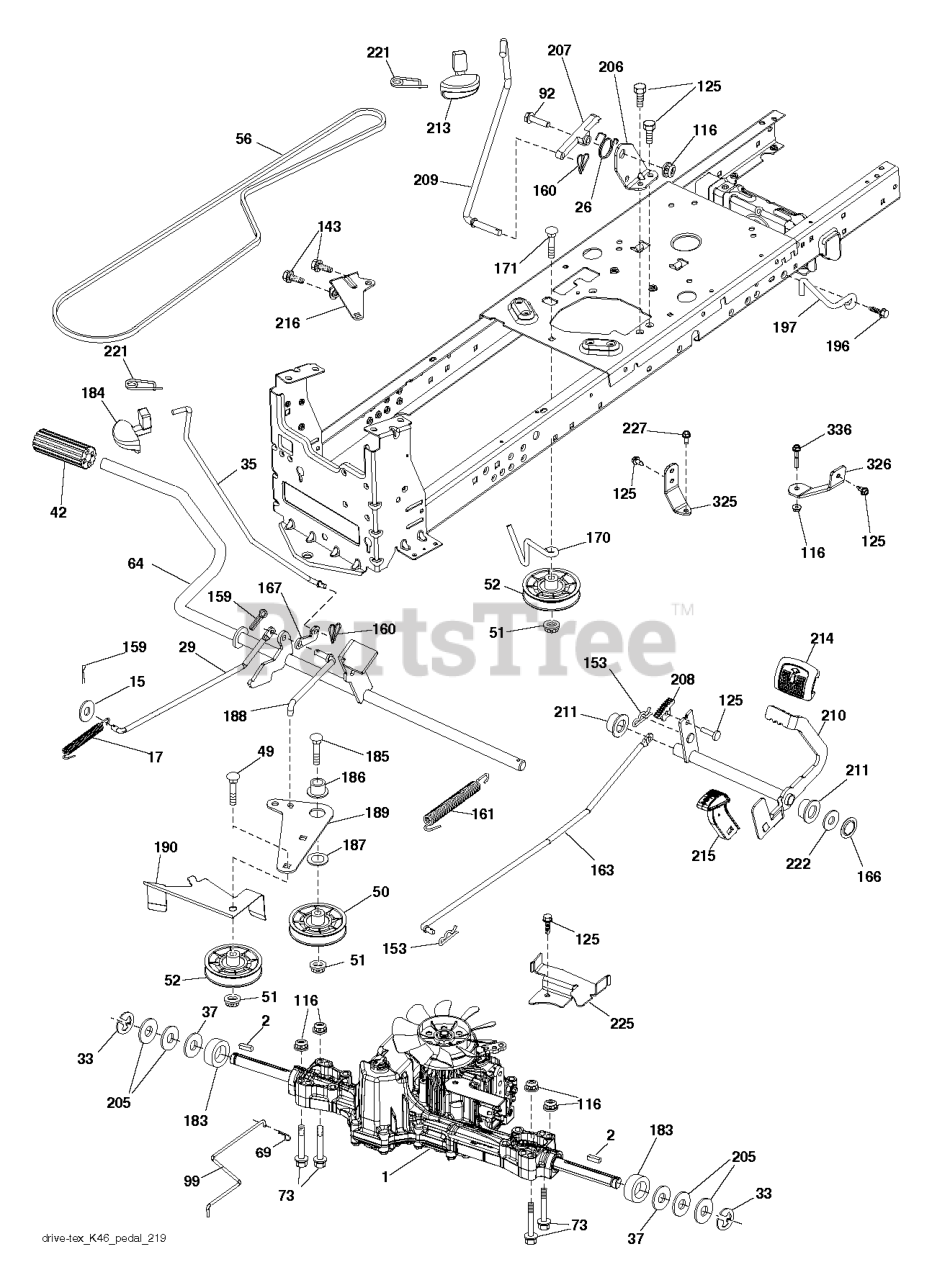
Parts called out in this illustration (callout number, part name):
2	SQUARE KEY
17	SPRING.BRAKE.K46.GREEN
26	SPRING.RETURN.CRUISE
29	ROD.BRAKE.K46
33	E-RING LT
37	WASHER.HARDENED
42	PEDAL COVER
50	IDLER.FLAT.910.OFFSET
51	NUT LOCK FLG 3/8-16 UNC
52	IDLER.V-GROOVE.910.OFFSET
64	SHAFT.ASM.PEDAL.BRK.CNTR
69	HAIRPIN.SOFT.ZINC.059X1.125
99	ARM.PIVOTING.TCRD.GEN2.5.BAGGE
116	GSPW Nuts
125	SCREW
153	RETAINER M
160	GSPW Retainers
161	SPRING, RETURN LT
166	NUT.PUSH.625
167	LATCH.BRAKE.SPRING
170	KEEPER.V-IDLER.CENTER.
183	SPACER AXLE
184	HANDLE.PARKING.BRAKE.H (BLK)
186	SPACER.RETAINER
188	LINK.CLUTCH.GROUND DRIVE.LONG
189	BELLCRANK.GROUND.DRIVE.TEX.
190	KEEPER.BELLCRANK.DRIVE
196	SCREW 3/8-16X1
206	BRACKET.MOUNT.CRUISE.LATCH
210	ROCKER.ASM.PEDAL.CONTR
211	BEARING.NYLON
213	KNOB.CONTROL.CRUSIE.HU
214	PEDAL.FORWARD.PAD.TEX
215	PEDAL.COVER.REVERSE.CRD.X428BK
216	BRACKET.PULLEY.IDLER.W/TEX
221	RETAINER.SPRING.CLIP.H
222	WASHER 21/32 X 1-1/4 X 10 GA.
225	KEEPER.BELT.TRANSAXLE.K46
325	BRACKET.TRQ.STP.46.20".TIRE.LH
326	BRCKT.PNT.TRQ.STP.46.20TIRE.RH
